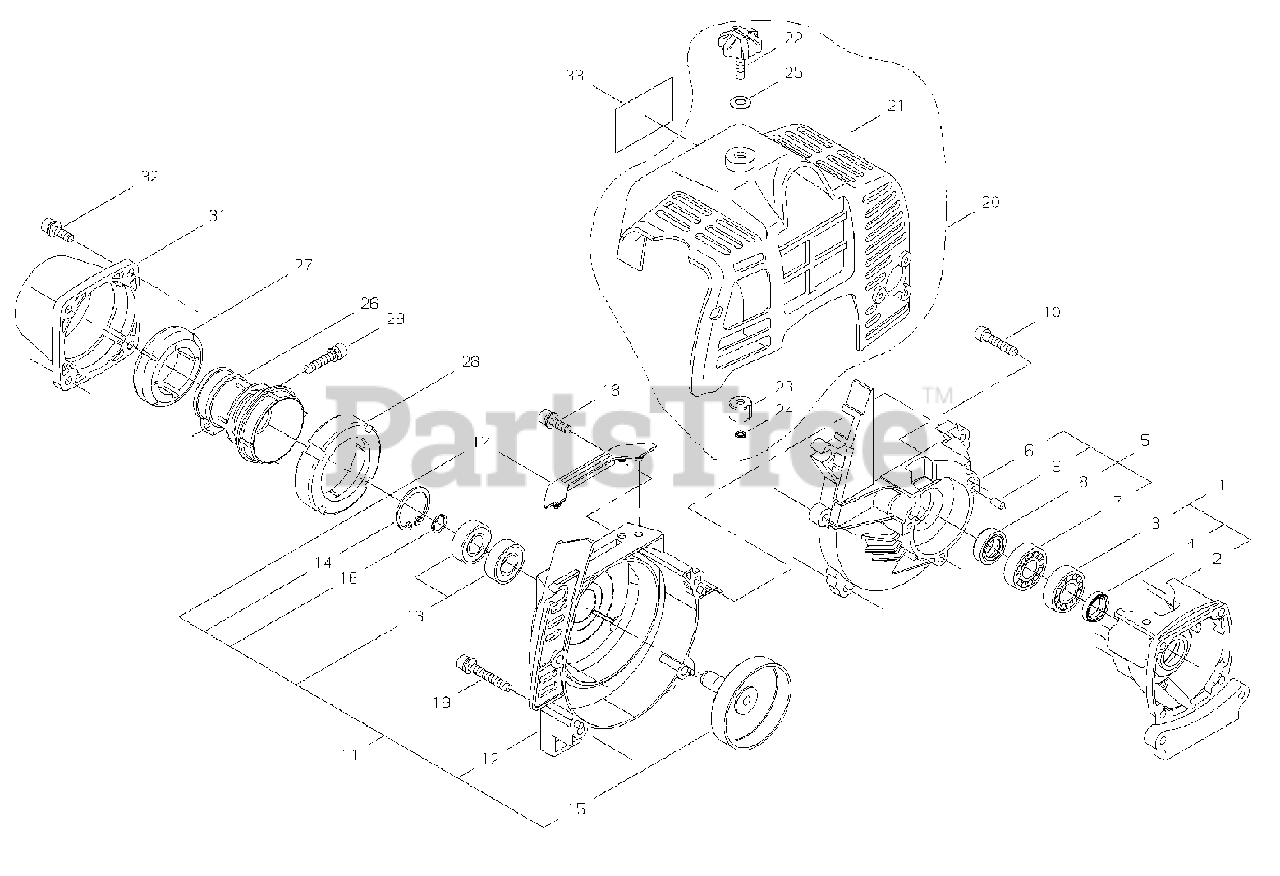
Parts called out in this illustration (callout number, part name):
2	CRANKCASE - REAR
3	BEARING, BALL - 6001C3
4	SEAL, OIL
5	CRANKCASE ASSY - FRONT
6	CRANKCASE - FRONT
7	BEARING, BALL - 6001C3
8	SEAL, OIL - 12
9	PIN - LOCATING
10	SCREW - 5X25
11	FAN COVER ASSY
12	CASE, FAN
13	BEARING, BALL - 6000
14	RING, RETAINING - 26
15	DRUM, CLUTCH
16	RING, RETAINING
17	CUSHION
18	SCREW - 5X16
19	SCREW - 5X45
20	CYLINDER COVER ASSY
21	COVER, CYLINDER
22	THUMBSCREW
23	INSULATOR
24	CLIP
25	WASHER - CONICAL
26	CLAMP, MAIN PIPE
27	CUSHION - FRONT
28	CUSHION - REAR
29	SCREW - 5X25
31	CAP
32	SCREW - 5X16
33	LABEL - TRADE
